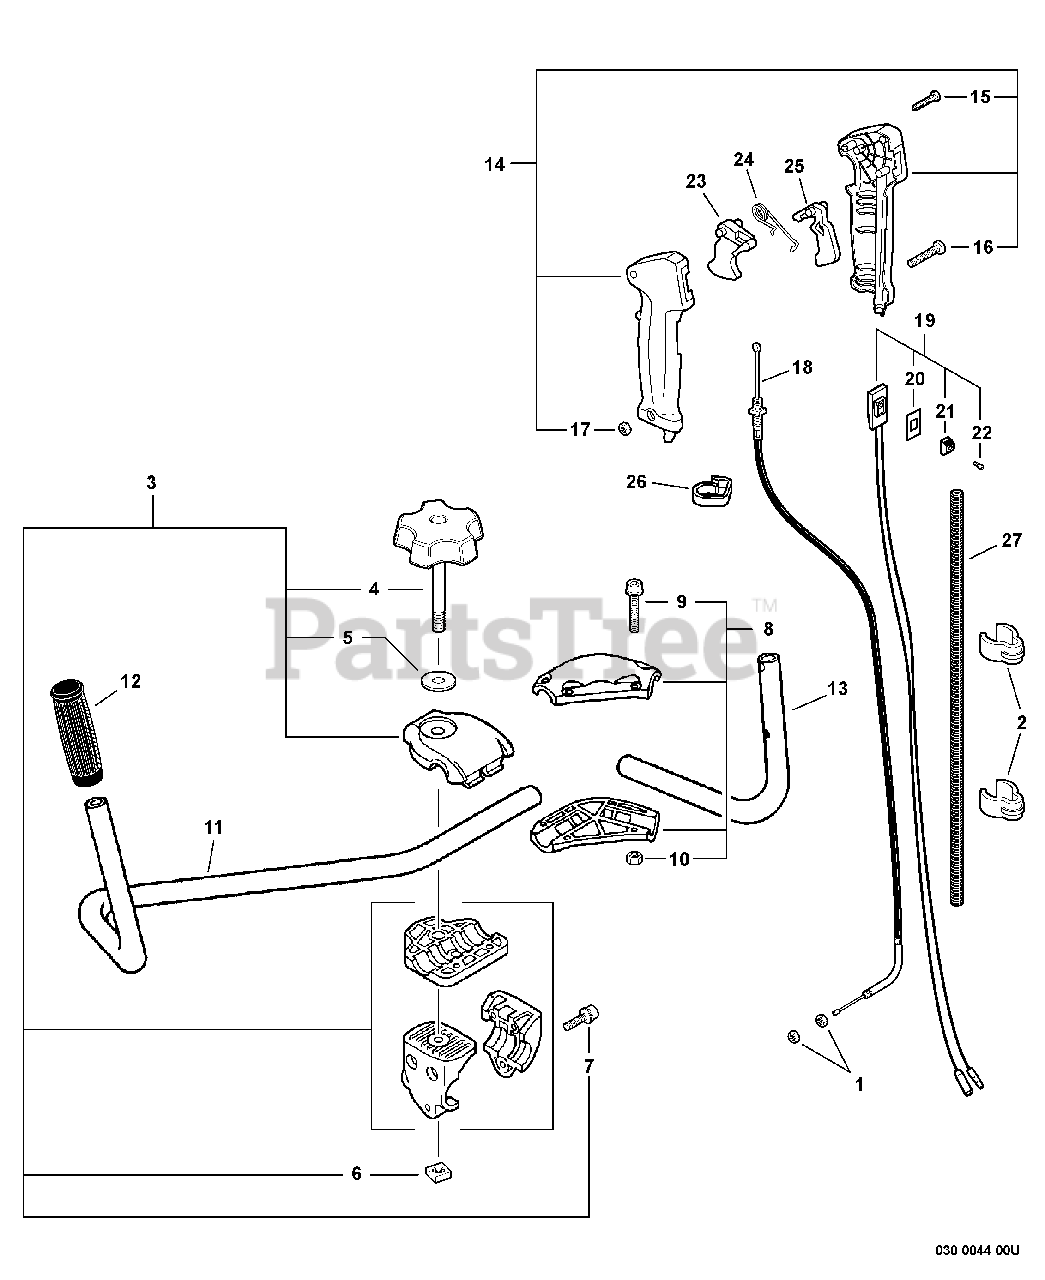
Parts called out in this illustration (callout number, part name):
3	HANDLE BRACKET KIT
4	THUMBSCREW
5	WASHER - 8
7	SCREW - 5X30
8	HANDLE BRACKET KIT
9	SCREW - 5X22
11	HANDLE, FRONT - LEFT
12	GRIP, HANDLE
13	HANDLE, FRONT - RIGHT
14	THROTTLE CONTROL ASSY
15	SCREW - 3X25
16	SCREW - 5X30
18	CABLE, THROTTLE
19	IGNITION SWITCH ASSY
20	COVER, SWITCH - STOP
21	KNOB, SWITCH - ORANGE
22	SCREW - 3X10
23	TRIGGER, THROTTLE
24	SPRING, LOCKOUT LEVER
25	LOCKOUT, THROTTLE
